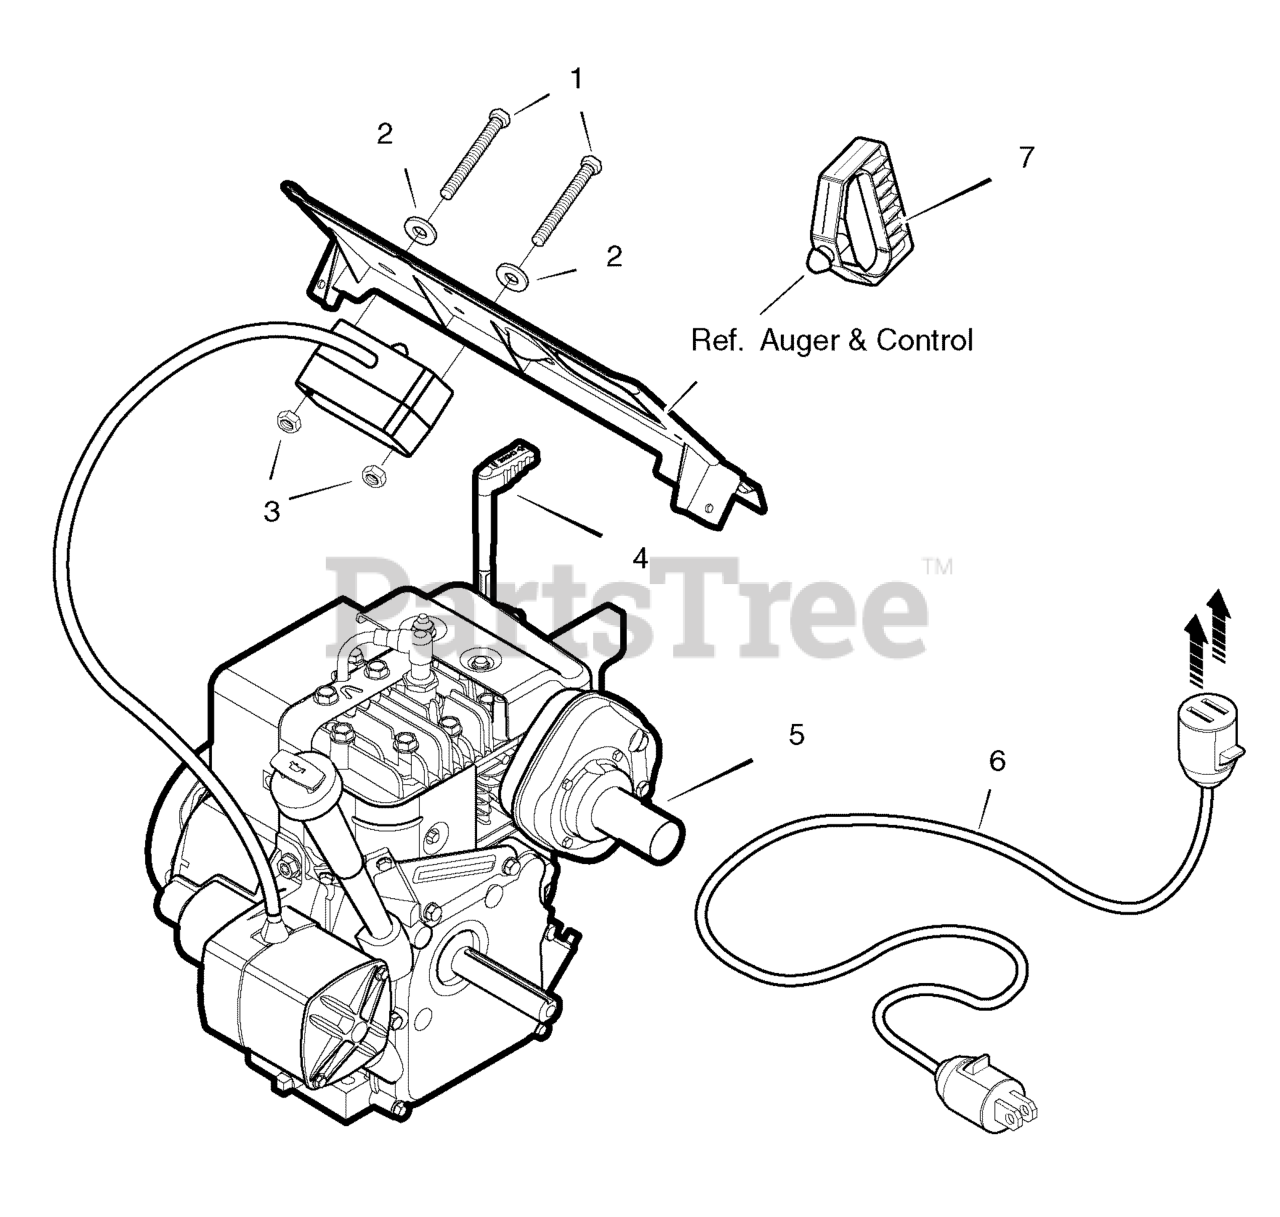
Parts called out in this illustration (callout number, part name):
1	SCREW, # 8 - 32 x 3
3	NUT, Keps
4	LEVER, Choke *
5-1	Muffler *
5-2	GASKET, Muffler *
5-3	Bolt, Muffler *
5-4	WASHER, Split Lock
5-5	NUT, Hex, 5/16 - 18
5-6	BOLT, Hex, 5/16 - 18
6	CORD, Electric, 10FT. 110V
7	GRIP, Starter Rope
